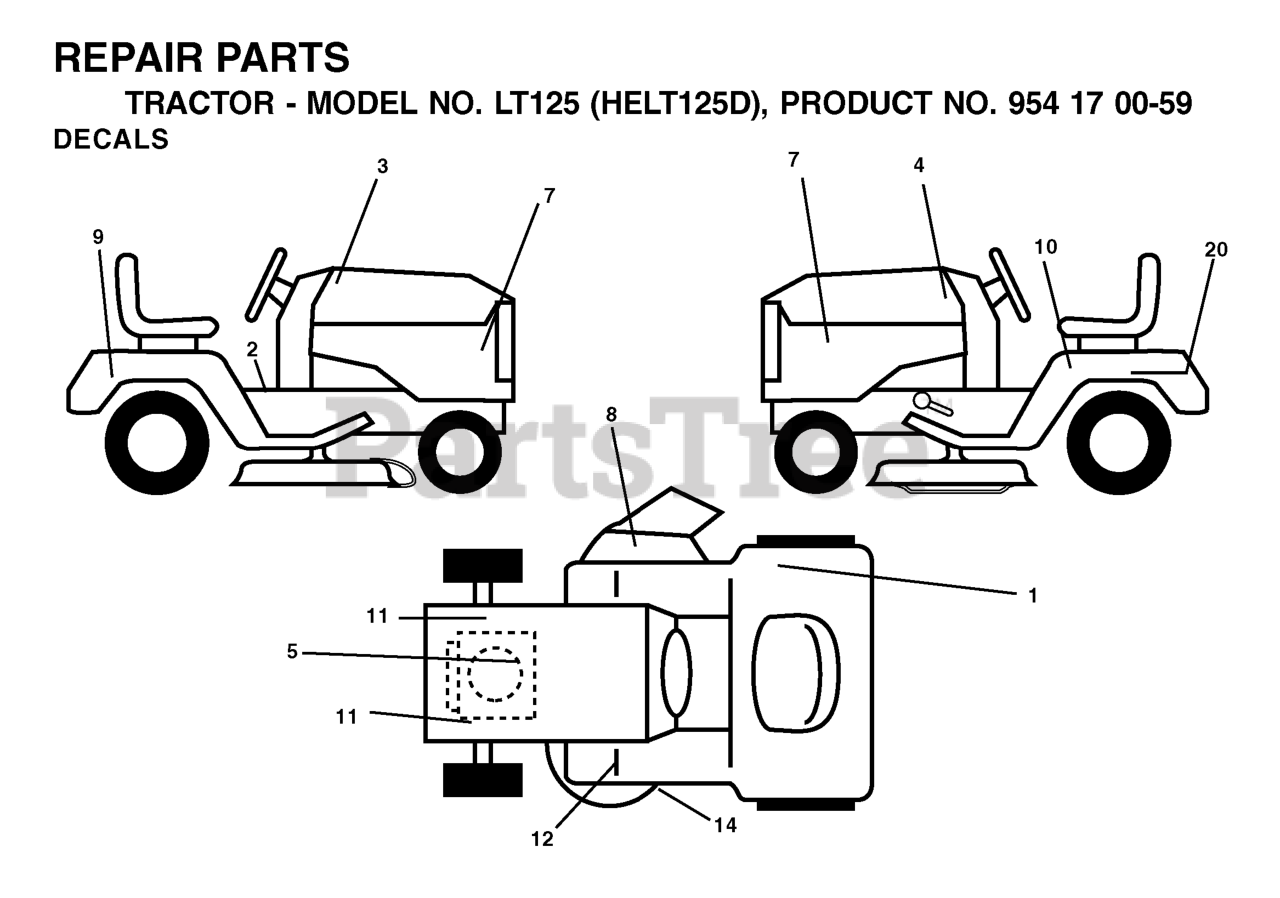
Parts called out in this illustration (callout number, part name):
1	Decal, Fender 100 DB/CE
2	DECAL PARK BRAKE
5	DECAL ENGINE HP
7	DECAL PNL SIDE
8	DECAL.INTERNATIONL.CUTFINGER
9	DECAL FENDER HUSQ
10	DECAL READ OWNER'S MAN SYMS
12	DECAL
14	DECAL V-BELT SCHEMATIC
20	DECAL BTRY SYMBOLS
